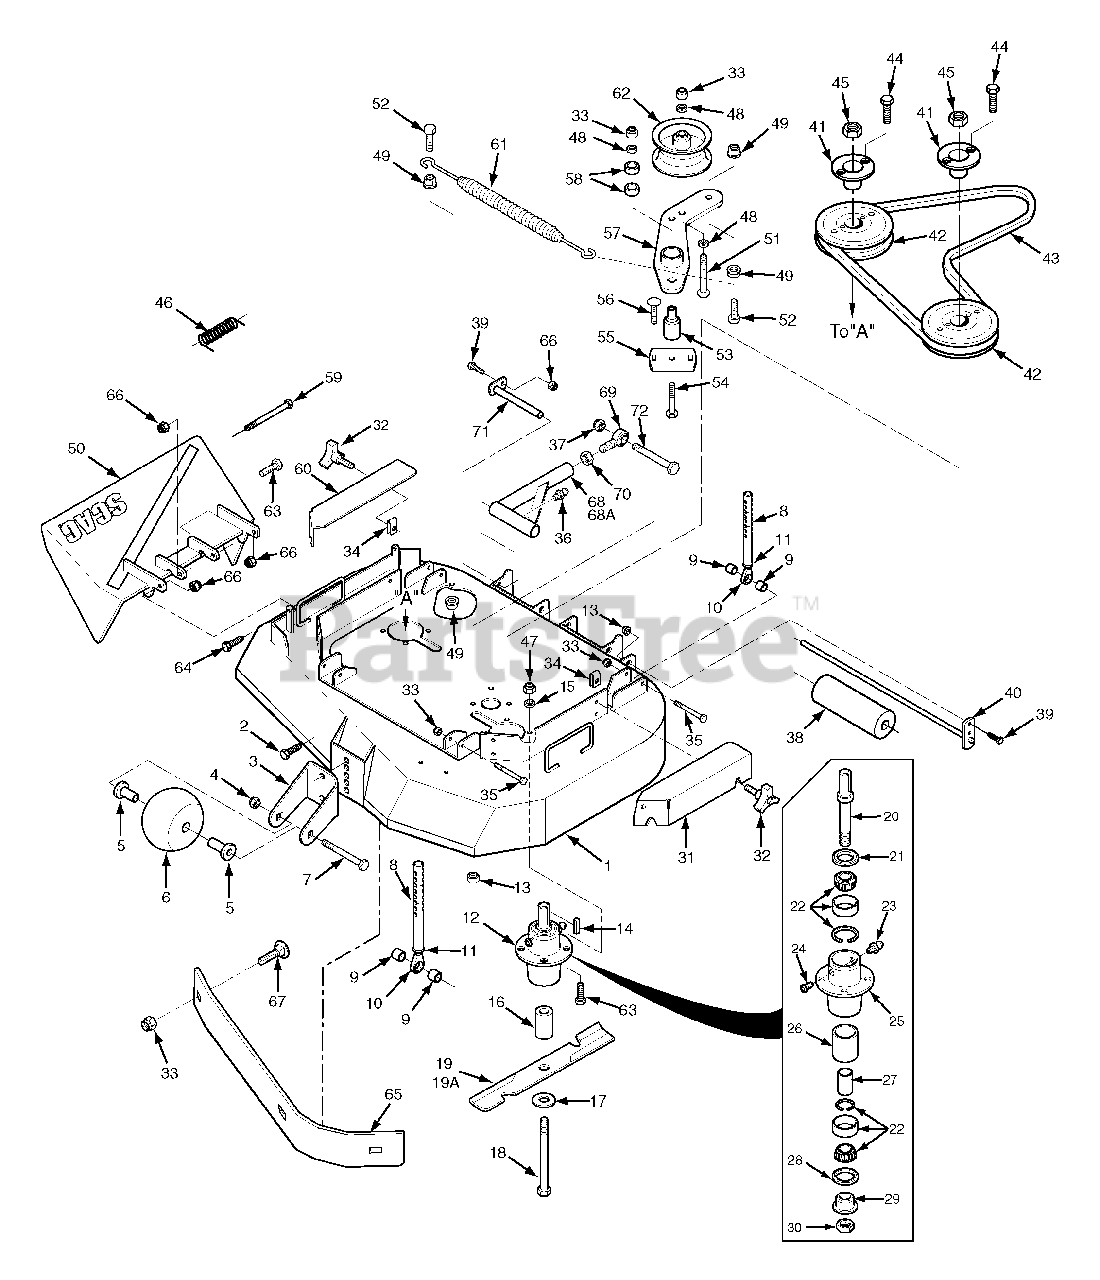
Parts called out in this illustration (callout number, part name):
1	Cutter Deck
2	Capscrew, 3/8-16 x 1.0" Serrated Flange Hex Hd
3	Bracket, Anti-Scalp Wheel
4	Lock Nut, 3/8-16 Center Lock
5	Bushing, .376" ID Oilite
6	Wheel, Anti-Scalp
7	Bolt, Carriage 3/8-16 x 4"
8	Pin Assy., Deck Adj.
9	Spacer, Deck Adjustment Pin
10	Rod End, Male 3/8-24 RH Thread
11	Nut, 3/8-24 Jam
12	Spindle Assembly
13	Nut, 5/16-18 Serrated Flange
14	Key,1/4" x 1/4" x 2"
15	Lock Washer 5/16"
16	Spacer, Spindle
17	Flatwasher, 5/8 W
18	Bolt, Hex Head 5/8-11 x 9-1/2"
19	Cutter Blade, 18"
19A	Cutter Blade, 18" Hi Lift
20	Spindle Shaft
21	Seal, Cutter Spindle Top
22	Tapered Bearing Set (Two Bearings W/Race)
23	Grease Fitting
24	Relief Fitting, Cutter Spindle
25	Spindle Housing
26	Spacer, Outside
27	Spacer, Inside
28	Seal, Cutter Spindle Bottom
29	Spindle Bushing
30	Nut, Spindle
31	Belt Cover, LH
32	Wing Nut, 3/8-16
33	Nut, 3/8-16 Elastic Stop
34	U-Nut, 3/8-16
35	Bolt, Hex Head 3/8-16 x 2-1/2"
36	Grease Fitting, 90 Degree
37	Nut, 1/2-13 Elastic Stop
38	Guide, Roller
39	Bolt, Hex Head 5/16-18 x 1"
40	Roller Shaft
41	Tapered Hub
42	Pulley
43	Belt, Cutter Deck
44	Bolt, Hex Head 1/4-20 x 1" Gr. 8
45	Hex Nut, 5/8-11
46	Spring, Chute Return
47	Lock Nut, 5/16-18 Elastic Stop Grade 8
48	Flatwasher, 3/8" (.938 x .391 x .105)
49	Nut, 3/8-16 Serrated Flange
50	Discharge Chute
51	Capscrew, Hex Head 3/8-16 x 3"
52	Capscrew, Hex Head 3/8-16 x 1-1/2"
53	Pivot, Idler
54	Capscrew, Hex Head 38/16 x 3-1/4"
55	Base, Idler Pivot
56	Bolt, Carriage 5/16-18 x 1"
57	Idler Arm Weldment
58	Ball Bearing
59	Bolt, Hex Head 5/16-18 x 4-3/4"
60	Belt Cover, RH
61	Spring, Deck Idler
62	Pulley, Idler
63	Bolt, Hex Head 5/16-18 x 1-1/2" Grade 8
64	Bolt, Hex Head 5/16-18 x 1-3/4"
65	Baffle Weldment
66	Nut, 5/16-18 Serrated Flange
67	Bolt, Carriage 3/8-16 x 1"
68	Push Arm - LH
68A	Push Arm - RH
69	Rod End, Male 1/2-20 RH Thread
70	Nut, 1/2-20 Jam
71	Push Arm Shaft
72	Bolt, Hex Head 1/2-13 x 3"
